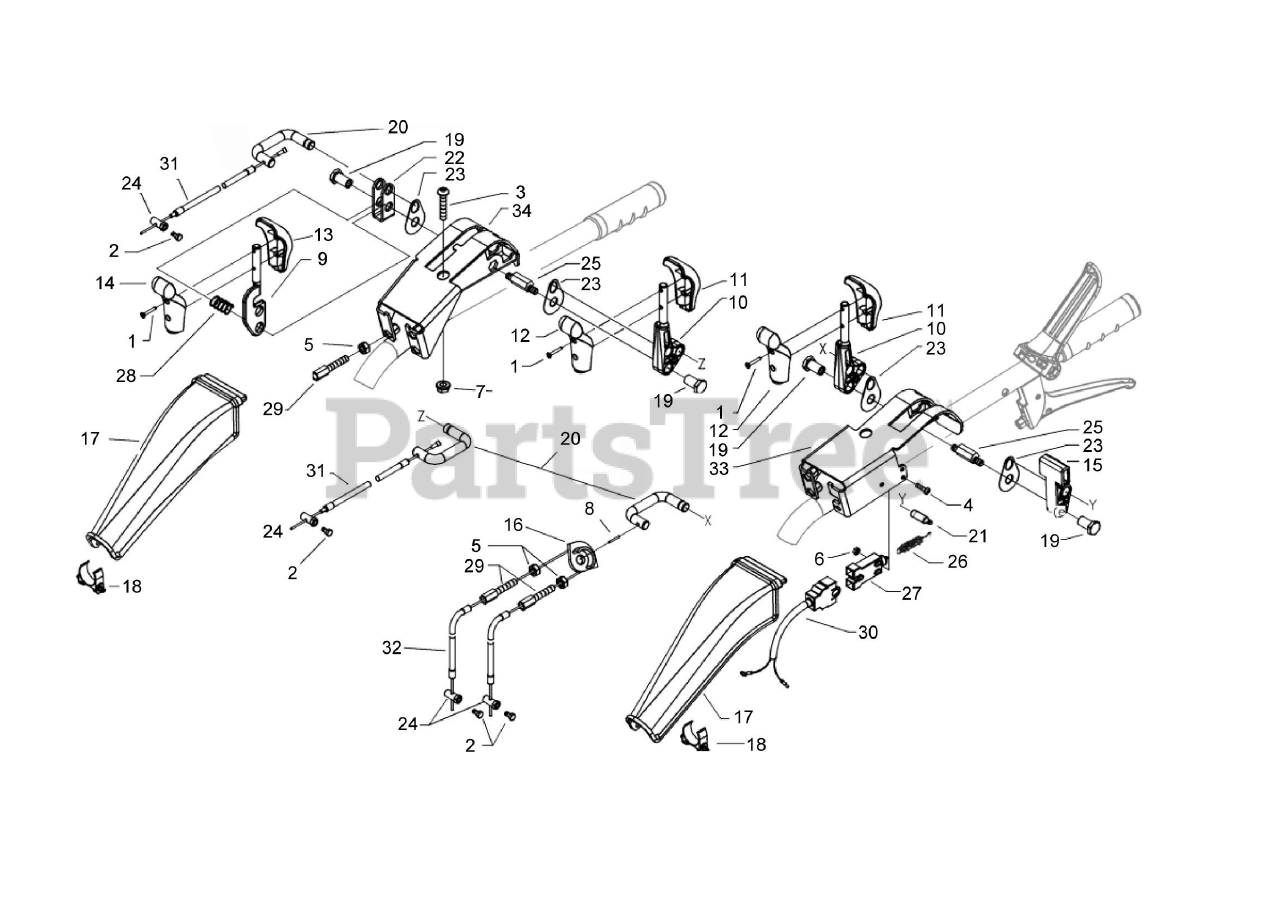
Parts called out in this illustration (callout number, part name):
1	SCREW 5X25
2	CAPSCREW M6X16
3	SCREW
4	INDEXING BOLT
5	NUT M8
6	SELF LOCKNUT M4
7	SELF LOCKNUT M8
8	ROLL PIN 4X20 SPIROL
9	LEVER, FORWARD / REVERSE
10	LEVER, LOCK DIFFERENTAL
11	UPPER HANDLE HALF, BLACK
12	LOWER HANDLE HALF, BLACK
13	UPPER HANDLE HALF, RED
14	LOWER HANDLE HALF, RED
15	LEVER, ON / OFF SWITCH
16	PULLEY
17	COVER
18	CROSS PIECE
19	STUD BOLT
20	U-BOLT
21	INDEXING BOLT
23	SMALL PLATE
24	SCREW, CLAMPING
26	SPRING
27	SWITCH
28	SPRING
29	ADJUSTING SCREW
30	WIRING, MOTOR STOP
31	CABLE & SHEATH, DIFFERENTIAL/REVERSE
32	CABLE & SHEATH, PARKING BREAK
33	SUPPORT LH
34	SUPPORT RH
